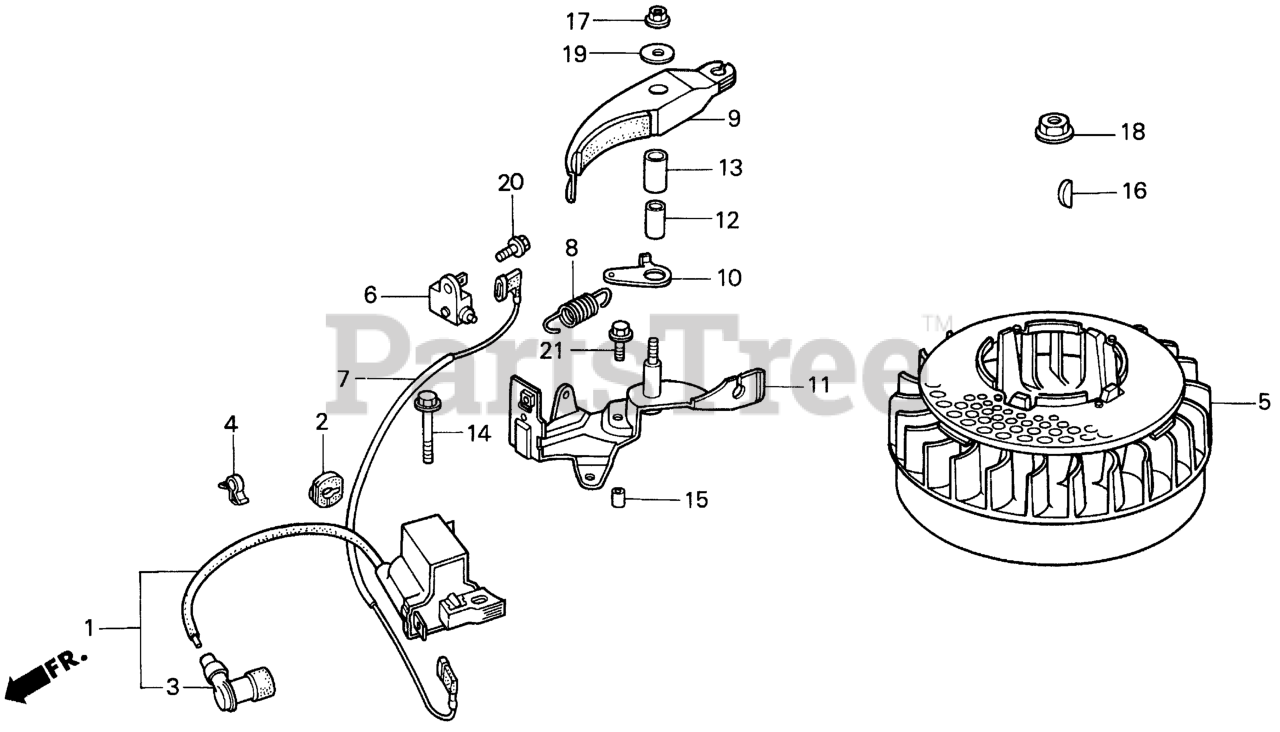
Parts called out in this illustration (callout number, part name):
1	COIL ASSY,IGN
2	GROMMET, IGNITION WIRE
3	CAP ASSY., NOISE SUPPRESSOR
4	CLIP, IGNITION WIRE (8MM)
5	FLYWHEEL ASSY.
6	SWITCH ASSY., ENGINE
7	WIRE, STOP SWITCH
8	SPRING, BRAKE
10	SPRING, LEVER
11	BASE, BRAKE
12	BUSH, BRAKE SHAFT
13	COLLAR, BRAKE SHAFT
14	BOLT, FLANGE (6X25) Use up to Engine SN 2056819.
15	PIN, DOWEL (8X10)
16	KEY, WOODRUFF (3MM)
17	NUT, FLANGE (6MM)
18	NUT, FLANGE (12MM)
19	WASHER, PLAIN (6MM)
20	BOLT, FLANGE (6X12) Use up to Engine SN 1543277.
21	BOLT, FLANGE (6X16) Use from Engine SN 2056820.
